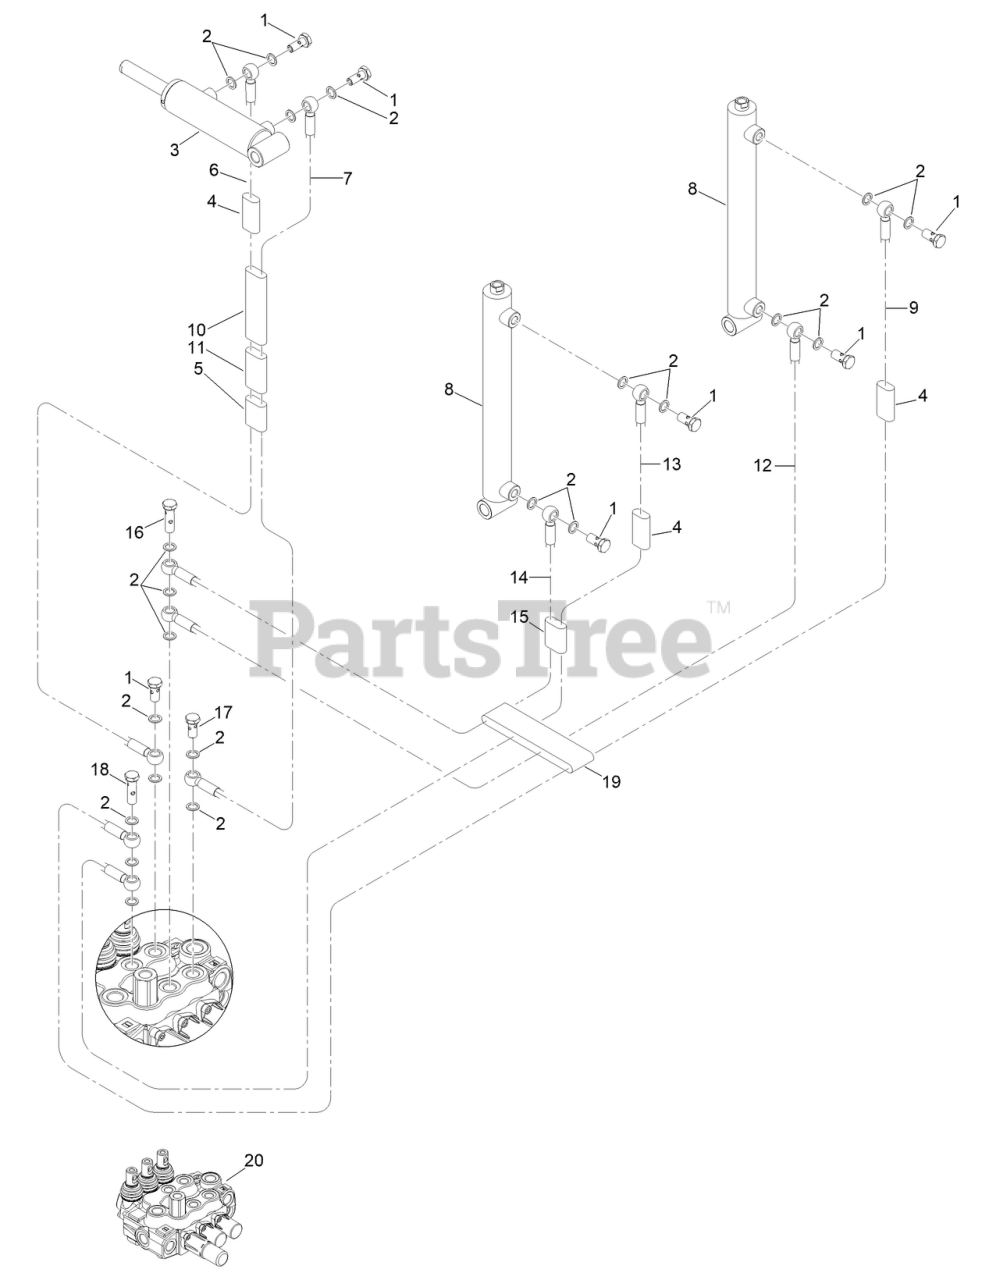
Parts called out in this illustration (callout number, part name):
2	WASHER
3	RAM, DUAL ACTING
4	PROTECTOR-HOSE
5	PROTECTOR-HOSE
8	CYLINDER
10	HOSE GUARD
11	HOSE GUARD
15	HOSE GUARD
19	HOSE GUARD
20	VALVE-LIFT
